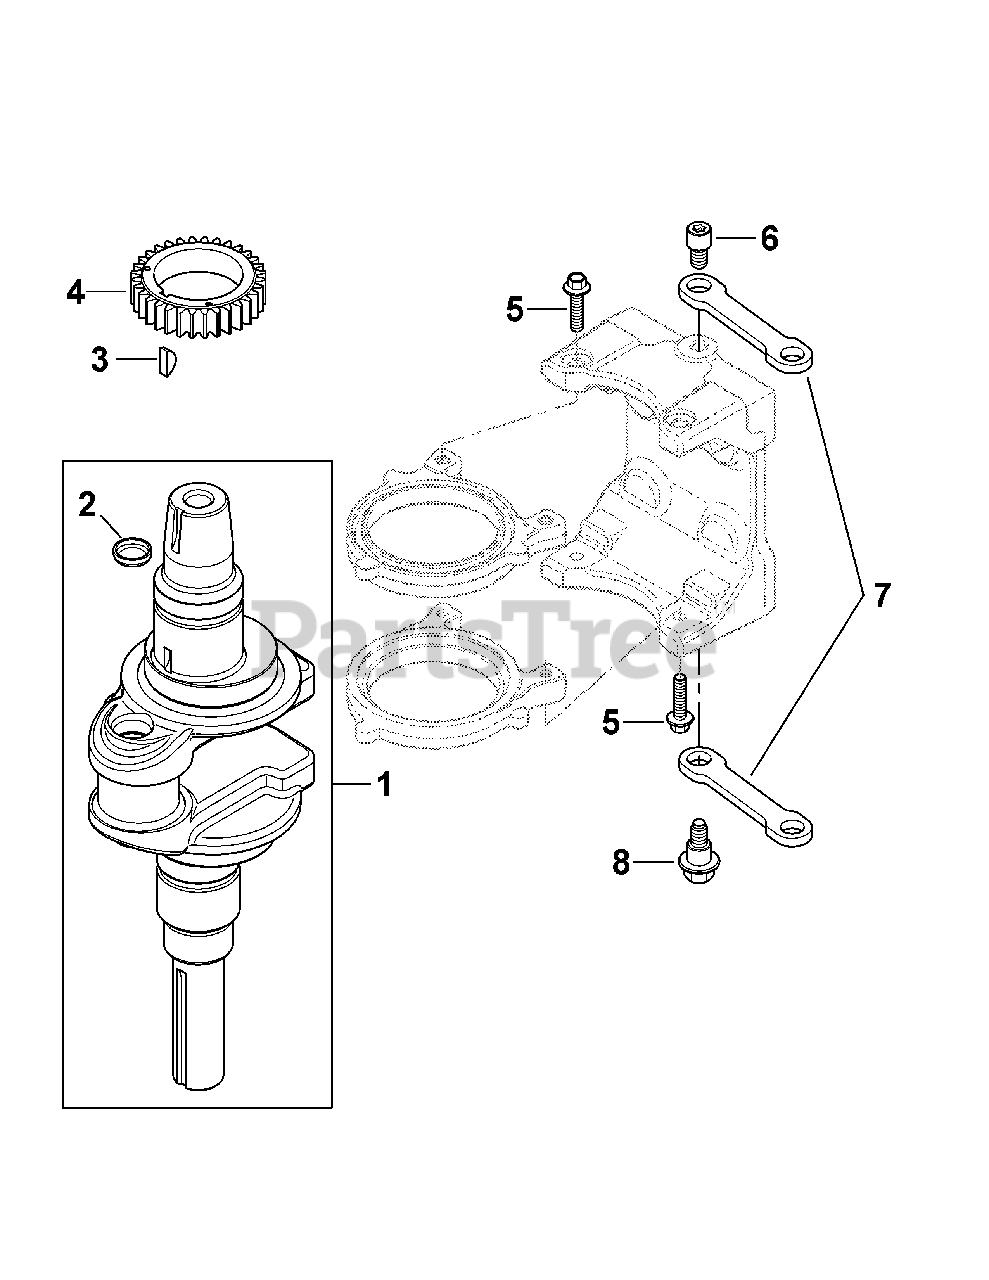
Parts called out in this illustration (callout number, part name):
1	Crankshaft Assembly Kit
3	Key, 3.16 X 5.8
4	Crankshaft Gear
5	Flange Screw, M6 X 1.0 X 25
6	Link Pivot Screw
7	Balance Weight Linkage
8	Shoulder Screw
9	Fuse Block
10	Fuse Block
11	Fuse Block
12	Fuse Block
13	Fuse Block
